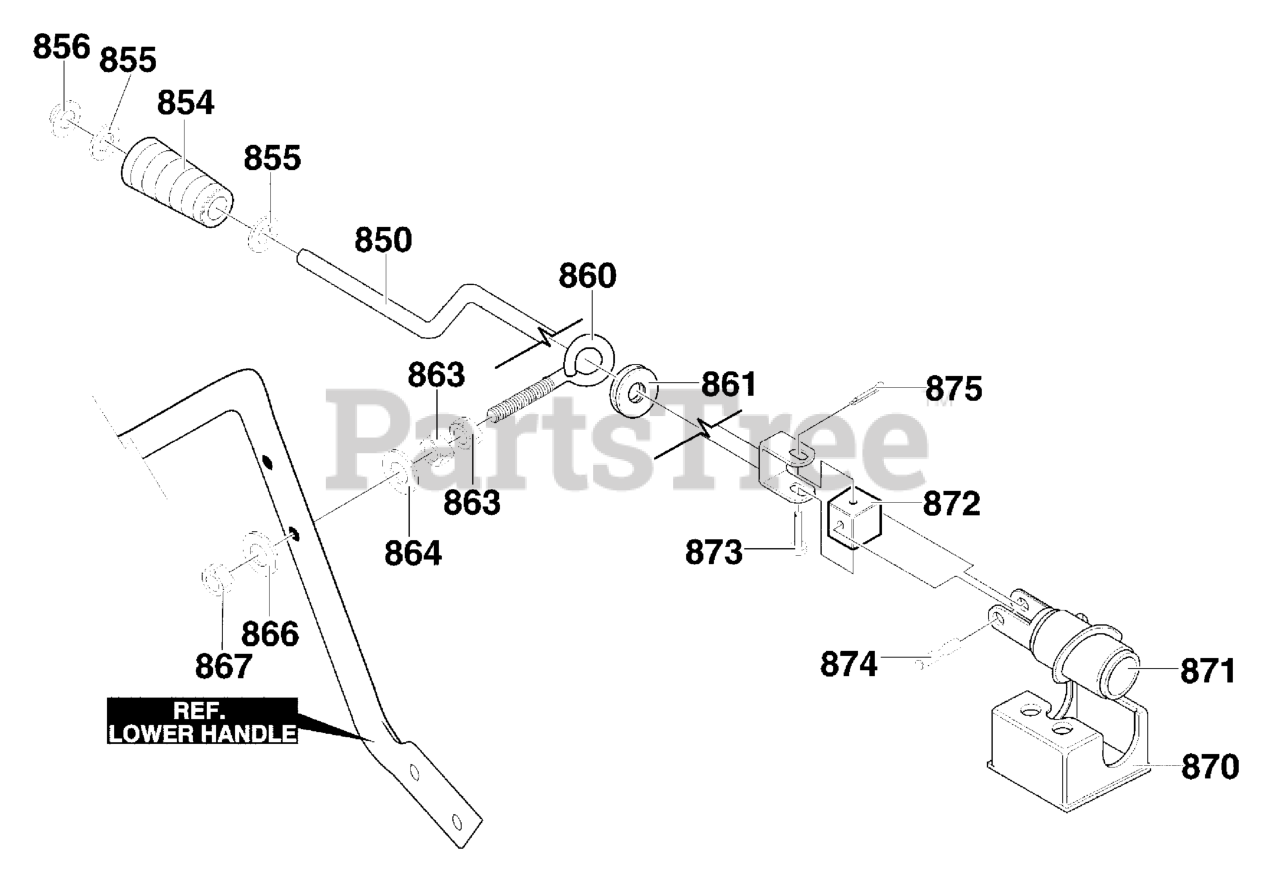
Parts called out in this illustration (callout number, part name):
850	CRANK ASSEMBLY
854	KNOB, SLEEVE
855	WASHER, FLAT
856	NUT, PUSH ON
860	BOLT, EYE
861	GROMMET, EYE BOLT
863	NUT, HEX JAM
864	WASHER, FLAT
866	WASHER, FLAT
867	NUT, HEX
870	BRKT, WORM
871	WORM, GEAR CHUTE
872	BLOCK, UNIV PIV
873	PIN, CLEVIS
874	PIN, UNIVERSAL JOINT
875	PIN, COTTER
